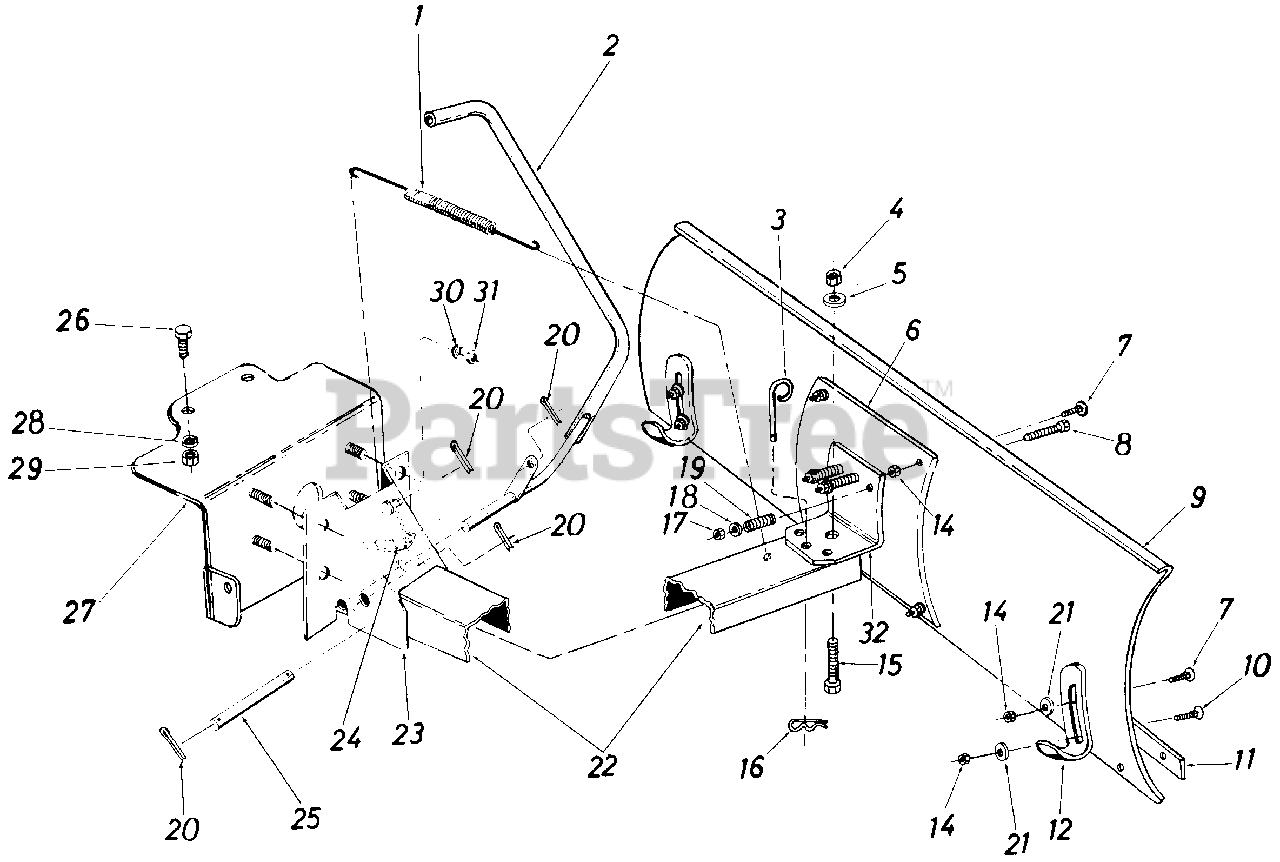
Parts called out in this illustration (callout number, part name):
1	Extension Spring
2	Lift Handle Ass'y.
3	Pivot Lock Pin
4	Hex Cent. L.-Nut 1/2-13 Thd.
5	Fl.-Wash. 17/32 I.D. x 1.25" Lg.
6	Reinforcement Plate
7	Carriage Bolt 5/16-18 x .75" Lg.*
8	Hex Scr. 3/8-16 x 3.75" Lg. Grade 5
9	42" Blade
10	Carriage Bolt 5/16-18 x 1.00" Lg.*
11	42" Wear Plate
12	Shoe Skid
14	Hex Cent. L.-Nut 5/16-18 Thd.*
15	Hex Scr. 1/2-13 x 1.25" Lg.*
16	Hair Pin Cotter
17	Hex Cent. L.-Nut 3/8-16 Thd.
18	Fl.-Wash. 3/8" I.D.
19	Compression Spring
20	Cotter Pin 1/8" Dia. x 1.00" Lg.*
21	Fl.-Wash. 5/16" I.D.
22	Push Bar Channel
23	Pivot Support Bracket
25	Channel Pivot Shaft
26	Hex Scr. 3/8-16 x 1.00" Lg. Grade 5
27	Support Bracket Ass'y.
28	L.-Wash. 3/8 I.D.*
29	Hex Nut 3/8-16 Thd.*
30	L.-Wash. 3/8" I.D.*
31	Hex Jam Nut 3/8-16 Thd.
32	Support Bracket
